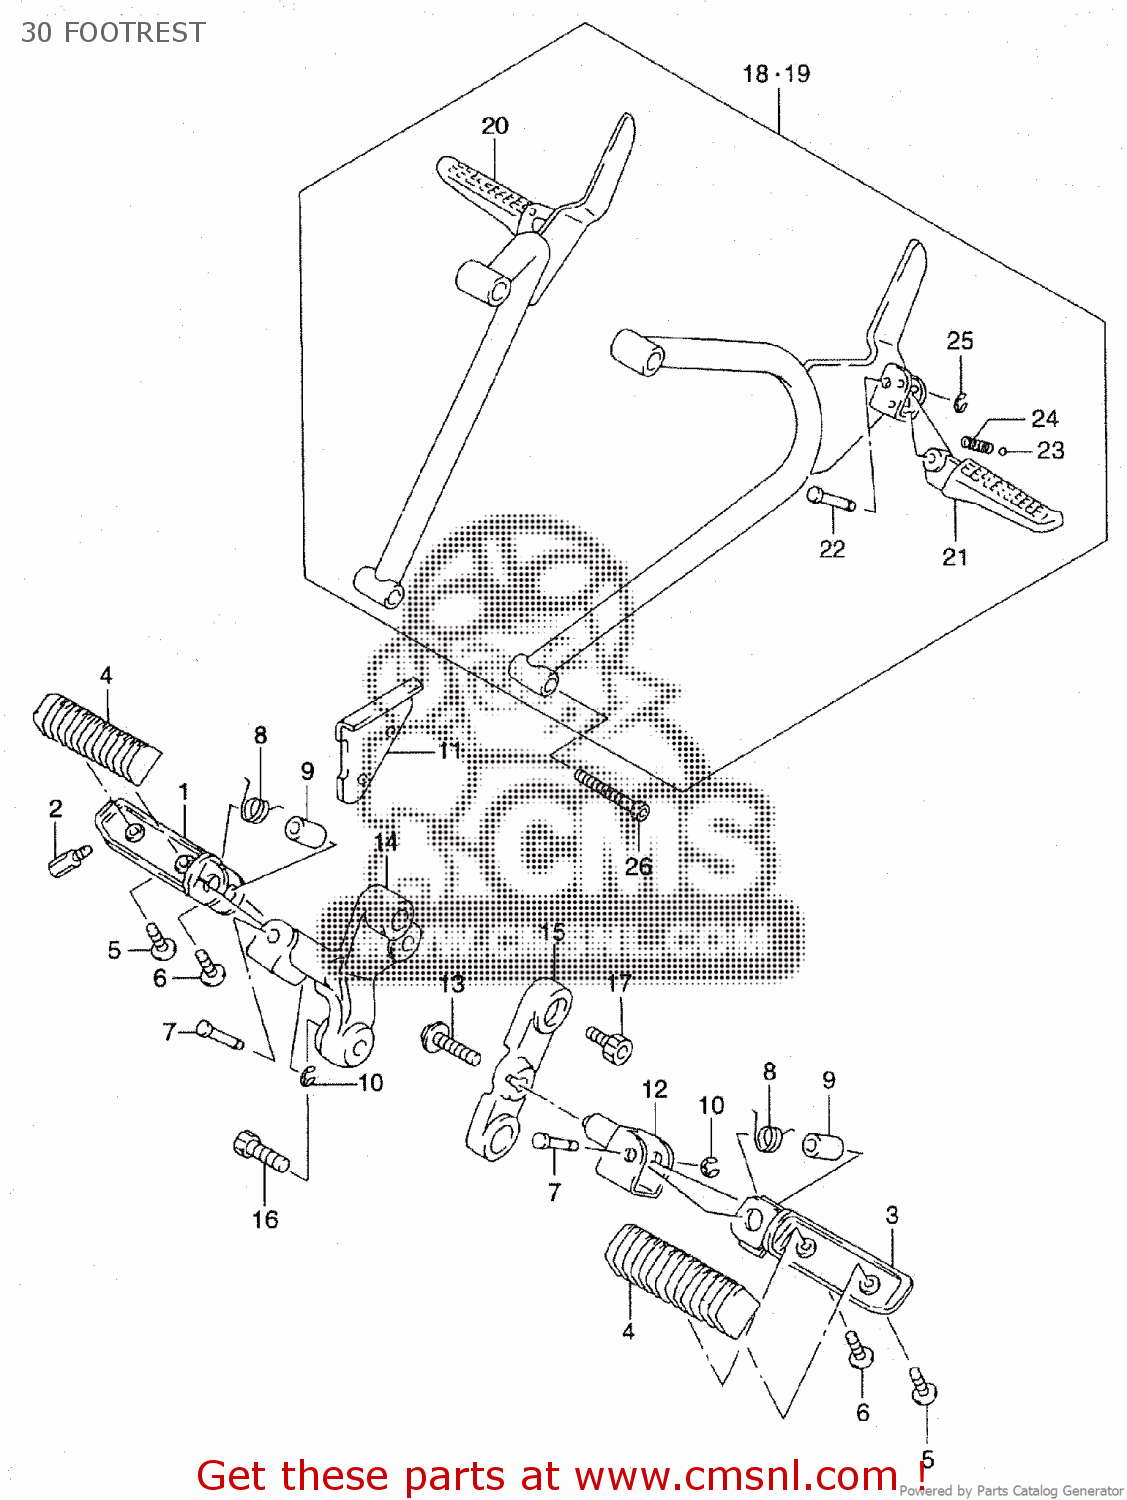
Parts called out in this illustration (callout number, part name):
1	BAR,FR FOOTREST,R
2	BOLT,BANK SENSOR
3	BAR,FR FOOTREST,L
4	RUBBER,FOOTREST
5	SCREW
6	SCREW 5X20
7	PIN(8X33.2)
8	SPRING
9	SPACER(8.1X12X22)
10	E.RING
12	FR FOOTREST HOL
13	BOLT(10X28)
16	BOLT
17	BOLT
20	BAR,PILLION FOOTREST,RIGHT
21	BAR,PILLION FOOTREST,LEFT
22	PIN
23	BALL
24	SPRING
25	E-RING
26	BOLT
